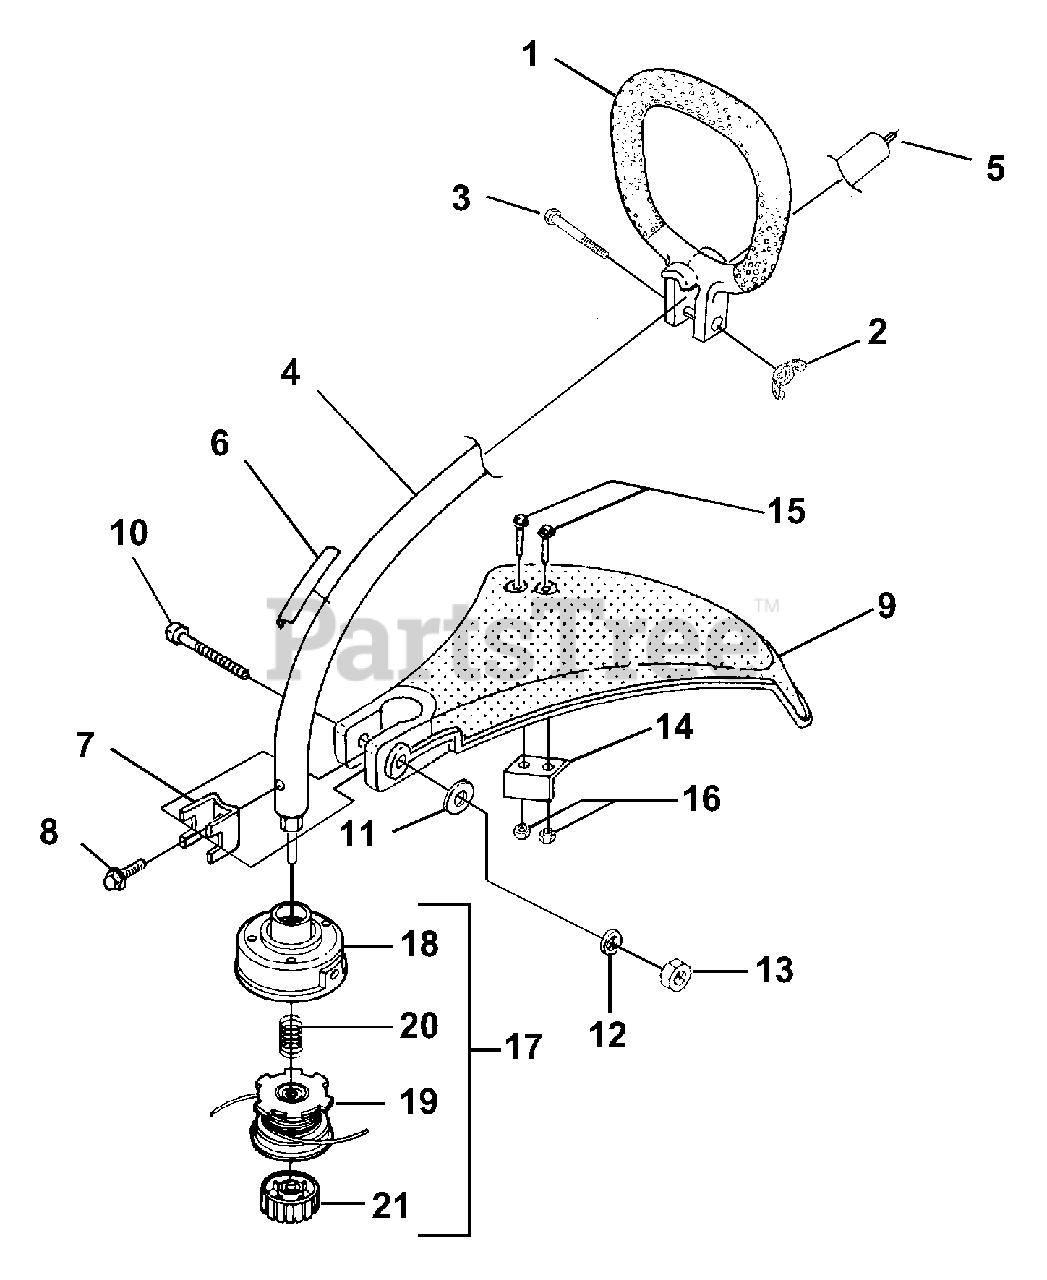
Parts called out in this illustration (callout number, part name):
1	HANDLE ASSY.-Front
2	NUT-Wing, Washer Faced (1/4-20)
3	SCREW-Cap Hex Hd.
4	DRIVESHAFT HOUSING ASSY.
5	SHAFT-Flexible
6	DECAL-Warning
7	CLAMP
8	SCREW-Sems Hex Hd. (#10-24 X 3/8")
9	DEFLECTOR & BLADE KIT (55 Deg.)
10	SCREW-Cap Hex Hd. (10-24 X 2")
11	WASHER-Flat (1/4")
12	WASHER-Lock (1/4")
13	NUT-Hex
14	BLADE-Cut-Off
15	SCREW-Mech. Hex Hd. (10-24 X 7/8")
16	NUT-Hex (10-24)
17	STRINGHEAD-Complete
18	HOUSING & EYELET (Dual Line)
19	SPOOL & STRING (.080" Line)
20	SPRING-Compression
21	RETAINER-Spool (R.H. Thread, Black)
